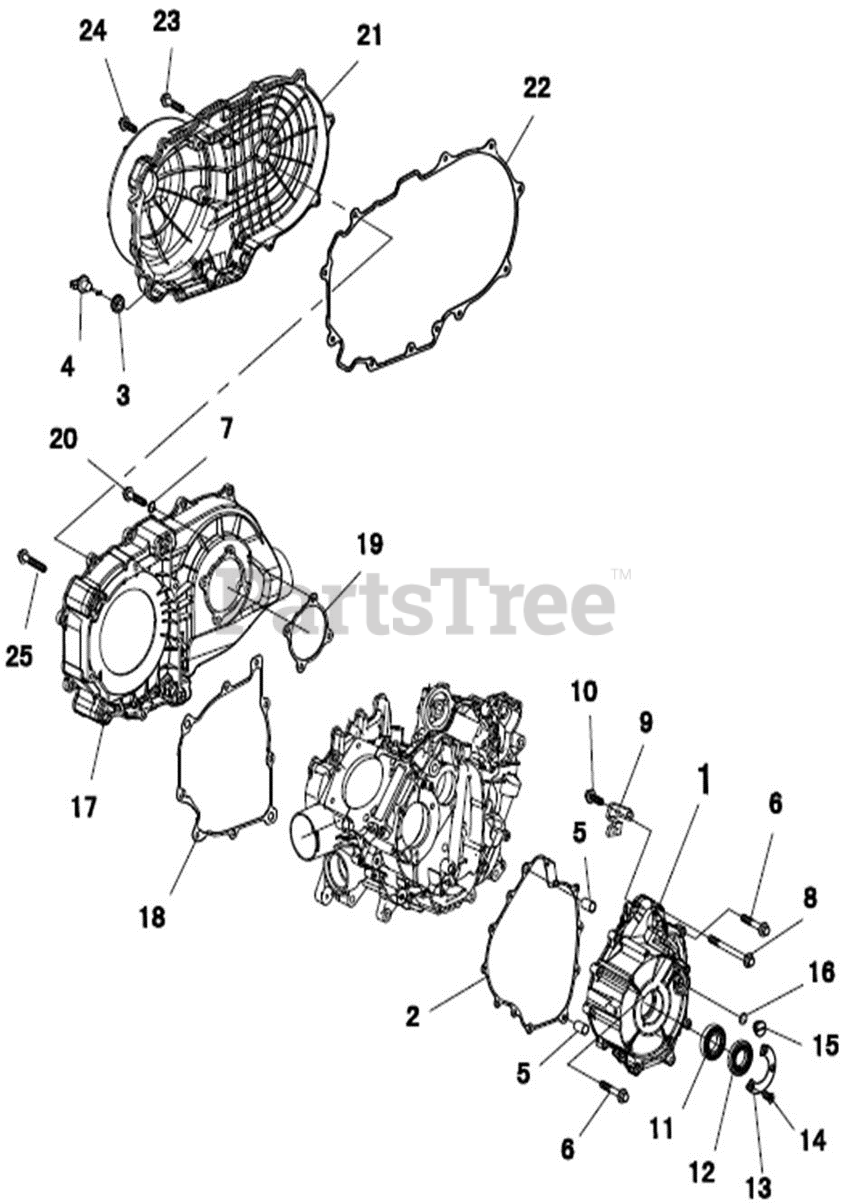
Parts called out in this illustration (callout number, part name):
1	LEFT CRANKCASE COVER
2	LEFT CRANKCASE COVER GASKET
4	CLUTCH COVER PLUG
5	DOWEL PIN 10X16
6	HEX FLANGE BOLTS M6X30
7	SPRING WASHER
8	HEX FLANGE BOLTS M6X40
9	STATOR WIRE GUARD PLATE
10	HEX FLANGE BOLT M6X12
11	BEARING 60/28
12	OIL SEAL 28X52X8.5
13	OIL SEAL PRESS PLATE
14	CROSS RECESSED COUNTERSUNK SCREW
15	SMALL PEEP HOLE COVER
16	O-RING 13.4X2.35
17	INNER CLUTCH COVER
18	CLUTCH INNER COVER SEAL
19	CLUTCH INNER COVERSEAL
20	HEX FLANGE BOLTS M6X32
21	OUTER CLUTCH COVER
22	CLUTCH COVER SEAL
23	HEX FLANGE BOLTS M6X25
24	HEX FLANGE BOLTS M6X16
25	HEX FLANGE BOLTS M6X50
